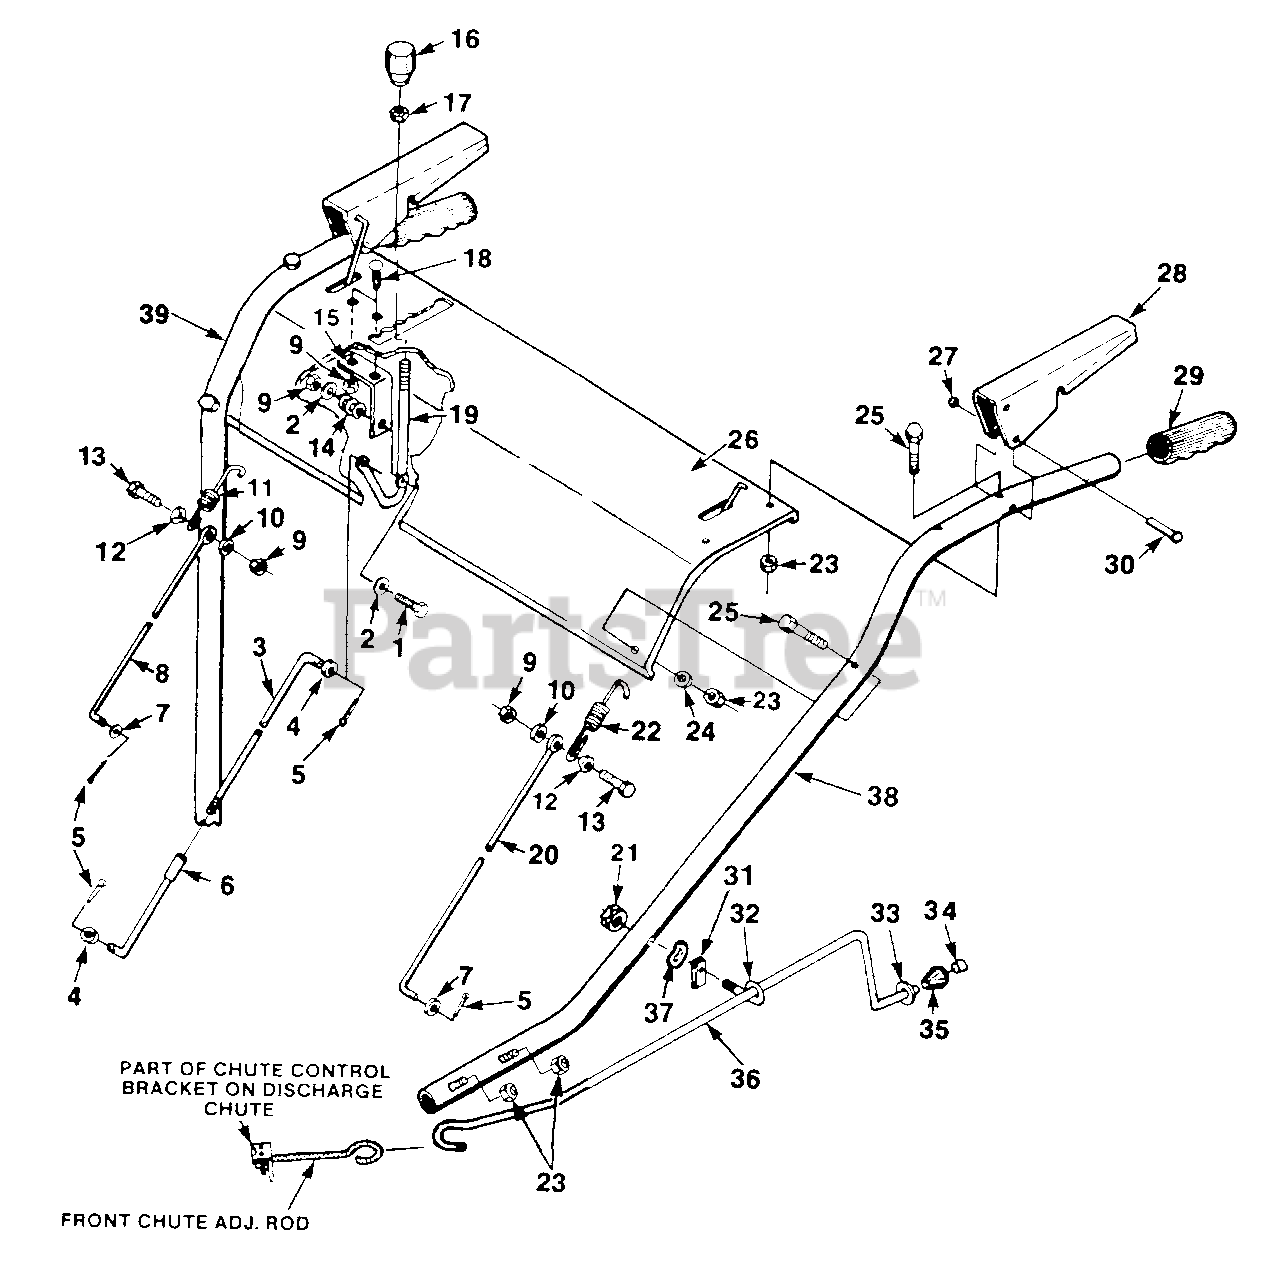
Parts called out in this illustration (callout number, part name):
1	SCREW- Speed control mtg. 1/4-20 x 2 1/2"
2	WASHER- Speed lever mtg.
3	ROD- Speed control (upper)
4	WASHER- Speed control mtg. 1/4"
5	PIN- Cotter 3/32 x 1/2"
6	ROD LOWER ASSEMBLY-Speed control
7	WASHER- Clutch rod mtg. #10 flat
8	ROD- Traction clutch
9	NUT- Centerlock clutch rod jam 1/4-20
10	WASHER- SAE flat 1/4"
11	SPRING- Extension
12	WASHER- Clutch rod joining
13	SCREW- Hex hd. clutch rod joining 1/4-20 x 7/8"
14	SPRING- Compression
15	BRACKET- Speed control mtg.
16	KNOB- Speed control
17	NUT- Hex jam 3/8-16"
18	SCREW- Truss hd. mach. 1/4-20 x 5/8"
19	LEVER- Speed control
20	ROD- Impeller-collector clutch
21	NUT- Hex NY lock chute adj. 1/4-20
22	SPRING- Extension
23	NUT- Hex c/lock handle & panel mtg. 5/16-18
24	WASHER- Flat handle and panel mtg. 5/16"
25	SCREW- Hex hd. cap Handle & Panel mtg. 5/16-18 x 1 1/2"
26	HANDLE PANEL (624)
27	NUT- Pal clutch grip mtg.
28	GRIP- Clutch control
29	GRIP- Handle
30	RIVET- Button hd. clutch grip mtg.1/4 x 1 1/2"
31	SPRING- Clutch rod
32	EYEBOLT- Chute Adj.
33	WASHER
34	NUT- Speed tinnerman
35	KNOB- Chute control
36	ROD- Chute adjusting
37	WASHER- Curved
38	HANDLE ASSY. (L.H.)
39	HANDLE ASSY. (R.H.)
